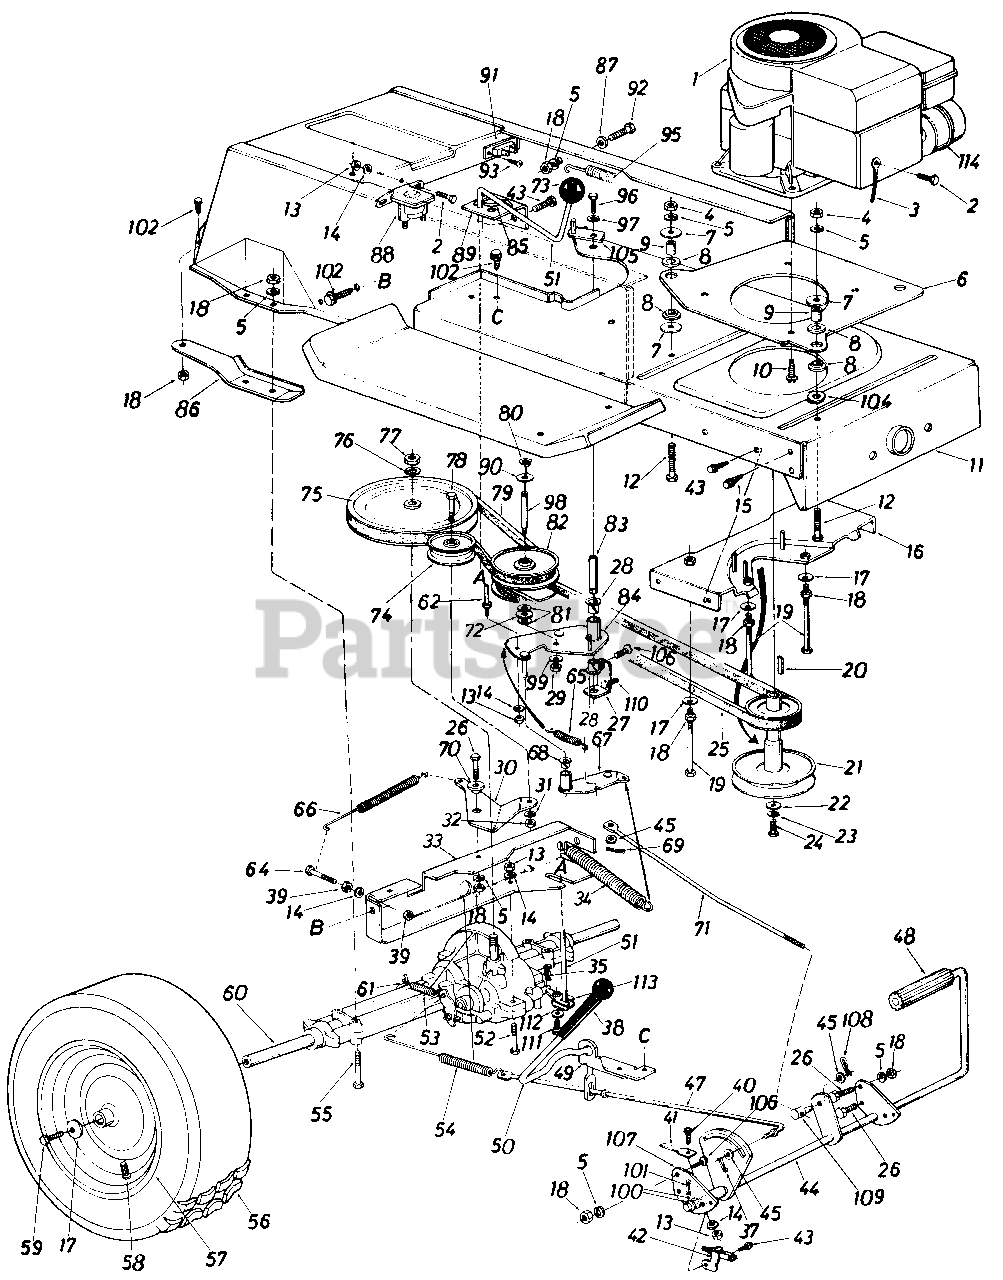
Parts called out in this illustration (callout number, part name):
1	Engine
2	Hex Bolt 1/4-20 x .62" Lg.*
3	Electric Ground Wire
4	Hex Nut 5/16-24 Thd.*
5	L-Wash. 5/16" I.D.*
6	Engine Mounting Plate
7	Fl-Wash. .320" I.D. x 1.25"
8	Engine Mounting Grommet
9	Spacer
10	Hex Bolt 3/8-16 x 1.25" Lg.
11	Lower Frame Ass'y.
12	Hex Bolt 5/16-24 x 1.25"*
13	Hex Nut 1/4-20 Thd.*
14	L-Wash. 1/4" I.D.*
15	Hex Wash Hd. AB-Tap Scr. 5/16" x .75" Lg.
16	Belt Guard Brkt. Ass'y.
17	Bell-Wash. .345" I.D. x .88"
18	Hex Nut 5/16-18 Thd.*
19	Hex Bolt 5/16-18 x 5.25" Lg.
20	Sq. Key 1/4 X 1/4 X 2.00
21	Engine Pulley
22	Fl-Wash. 7/16" I.D. x 1.25"
23	L-Wash. 7/16" I.D.*
24	Hex Bolt 7/16-20 x 1.50" Lg.
25	Variable Speed Belt
27	Bearing Shaft Bracket Ass'y.
28	Flanged Nyliner Brg. 518" I.D. x .88" Lg.
29	Hex Nut 3/8-24 Thd.*
30	Idler Bracket
31	L-Wash. 3/8" I.D.*
32	Hex Nut 3/8-24 Thd.*
33	Transaxle Support Brkt.
34	Ext. Spring .94" O.D. x 6.7
35	Inter. Cott-Pin
37	Cotter Pin 3/32" Dia. x .75"*
39	Hex Nut 1/4-28 Thd.
40	Hex Bolt 1/4-20 x 1.00" Lg.*
41	Switch Actuator
42	Safety Switch
43	Hex Wash. Hd. S-Tap Scr. 1/4-20 x .50" Lg.
44	Clutch & Brake Pedal Ass'y.
45	Fl-Wash.
47	Brake Rod 20.9" Lg.
48	Foot Pad
49	Brake Lever Bracket
50	Hill Holder Brake Handle
51	Shift Lever Ass'y.
52	Hex Bolt 1/4-28 x 1.75" Lg.*
53	Ext. Spring .38" O.D. x 2.5"
54	Ext. Spring .59" O.D. x 7.08"
55	Hex Bolt 5/16-18 x 2.75"*
58	Air Valve
59	Hex Bolt 5/16-24 x .75" Lg.*
60	Transaxle Complete
61	Brake Return Spring Anchor
62	Belt Guard Pin 1/4-20 Thd.
64	Hex Bolt 1/4-28 x 1.25" Lg.
65	Ext. Spring .50" Dia.
66	Ext. Spring .62" O.D. x 6.12"
67	Variable Speed Torque Brkt. Ass'y.
68	Flanged Bearing
69	Cotter Pin 3/32" Dia.
70	Shoulder Spacer .500" Dia. x.27" Lg.
71	Speed Control Link
72	Truss Bearing .56 Dia. x 1 .25"
73	Knob
74	Fl-ldler Pulley 3.25" x 1.0"
75	1/2" "V"-Pulley 8.0" O.D. x .501" I.D.
76	L-Wash. 1/2" I.D.
77	Hex Jam Nut 1/2-20 Thd.
78	Hex Bolt 3/8-24 x .75" Lg.
79	Variable Speed Belt
80	Snap Ring .56" Dia.
82	Variable Speed Pulley Ass'y. 5" O.D.
83	Bearing Shaft
84	Variable Speed Brkt. Ass'y.
85	Comp. Spring-Clip
86	Transaxle Support Brkt.-R.H.
87	Fl-Wash. .34 I.D. x 1.12 O.D.
88	Solenoid
89	Shift Lever Bracket
90	Teflon Washer
91	Circuit Breaker
92	Hex Bolt 5/16-18 x 1.50" Lg.
93	Truss Hd. Phil. Scr. #10 x 1/2 " Lg.
95	Ext. Spring .99" O.D. x 11.0"
96	Hex Bolt 3/8-24 x .75" Lg.
97	Bell-Wash. .38" I.D. x .88"
98	Shaft .56" Dia. x 3.875" Lg.
99	Bell-Wash. .39" I.D. x 1.12"
100	Fl-Wash.
101	Cotter Pin 3/32" Dia. x 1.0"
102	Hex Wash. Hd. Scr. 5/16-18 x.62" Lg.
104	Fl-Wash. .32" I.D. x 1.25"
105	Belt Guard
106	Truss Mach. Scr. 5/16-18 x .75" Lg.
107	Pedal Bracket
108	Cotter Pin 3132" Dia. x .75"
109	Ferrule
110	Truss Phillips Hd. Scr. 5/16-18 x 1.0" Lg.
111	Hex Bolt 1/4-28 x .50" Lg.
112	Bell-Wash. .265" I.D. x .75"
113	Shift Lever Link Ass'y.
114	Muffler
